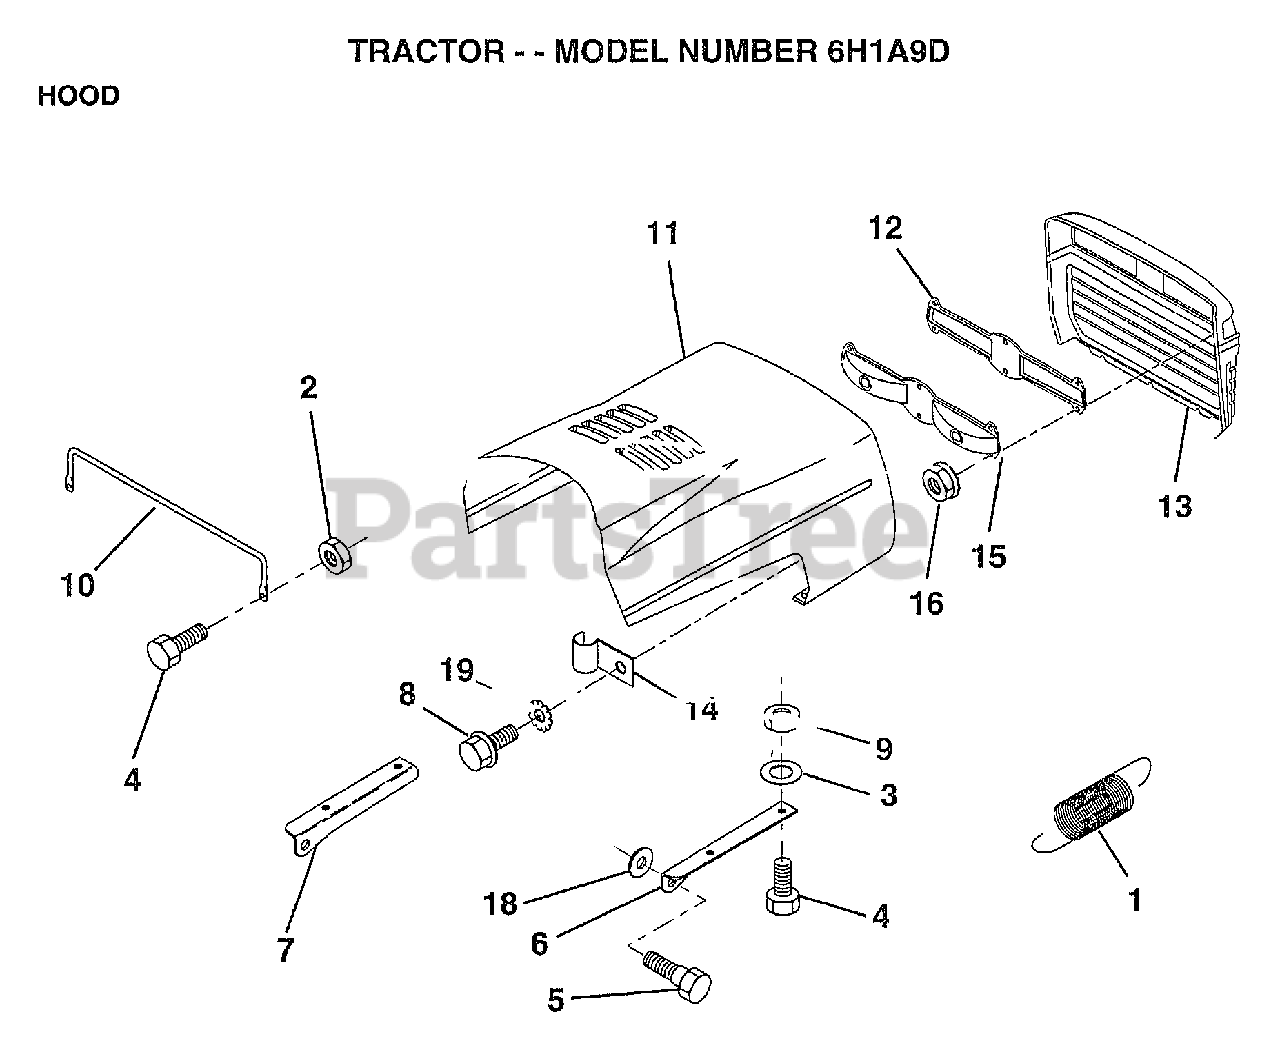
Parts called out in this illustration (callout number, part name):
1	EXT SPRING
2	NUT HXKEP 1/4X20
3	WASHER
5	BOLT.SHLD.5/16-18
6	BRKT HOOD RH
7	BRKT HOOD LH
8	SCREW SLTD HXHD
9	NUT
10	"BRACE,HOOD"
11	HOOD
13	GRILL (BLACK)
16	NUT
18	WASHER
19	LOCKWASHER GT
